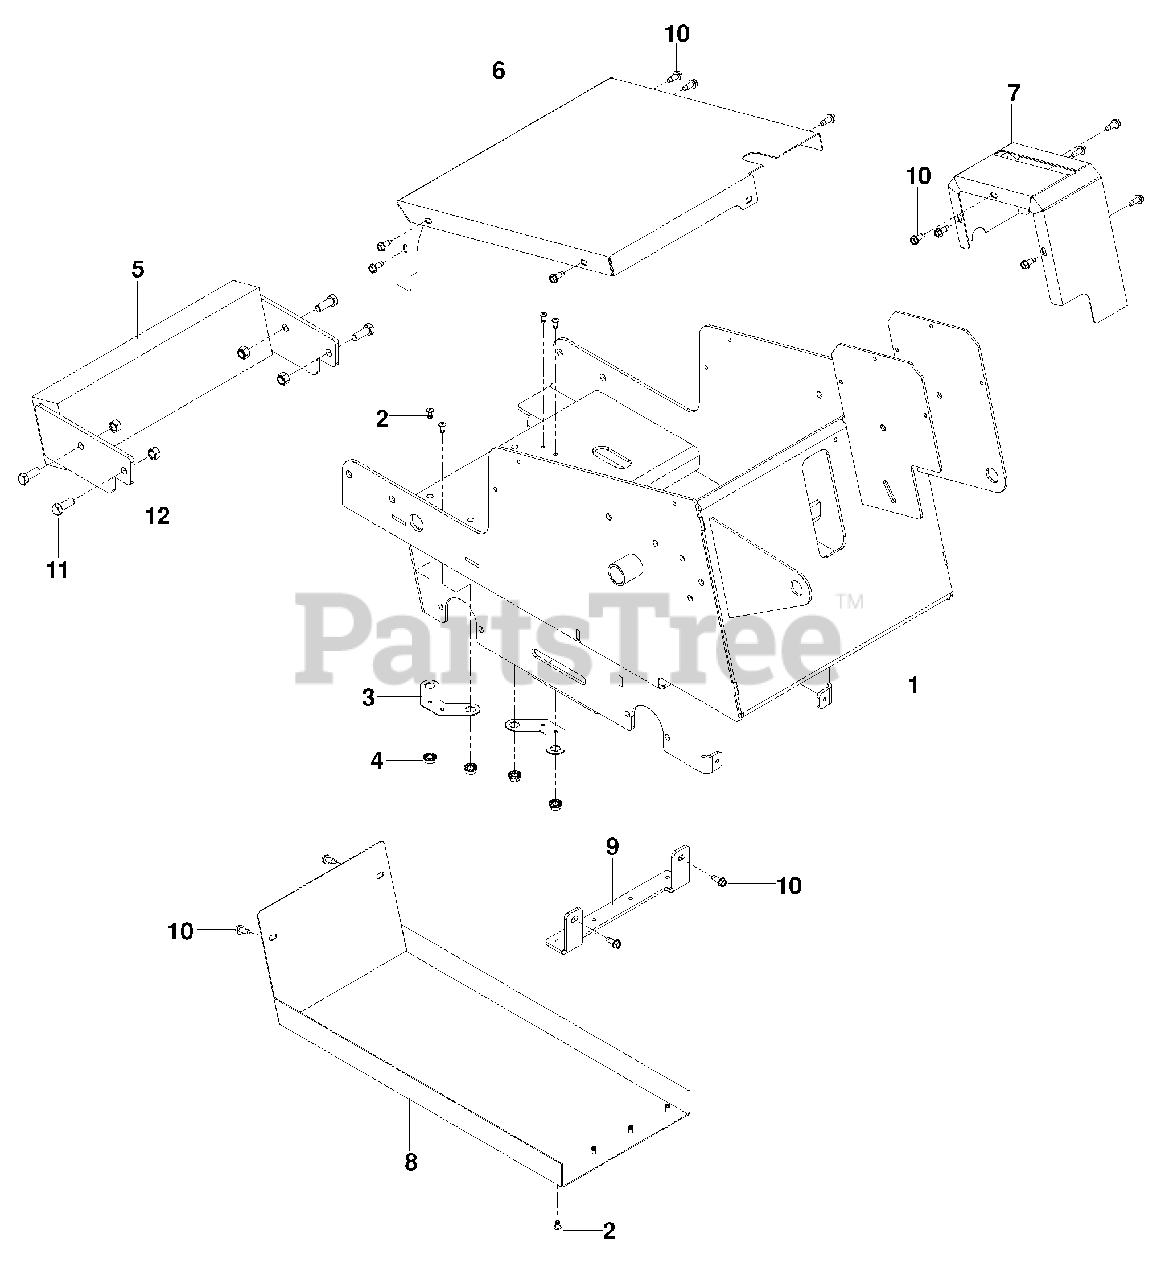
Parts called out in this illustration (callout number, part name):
1	FRAME, ORG
2	RIVET 3/16 STAVEX
4	NUT 5/16-18 FLG NYLOC
5	FRONT WEIGHT
6	COVER, TOP, ORG
7	COVER, SHIFT, ORG
8	BELLY PAN, ORG
9	END BRACKET, ORG
10	SCREW 1/4-20 x 5/8 SELF TAP
11	HCS 3/8-16 x 1
12	NUT 3/8-16 HEX NYLOC
